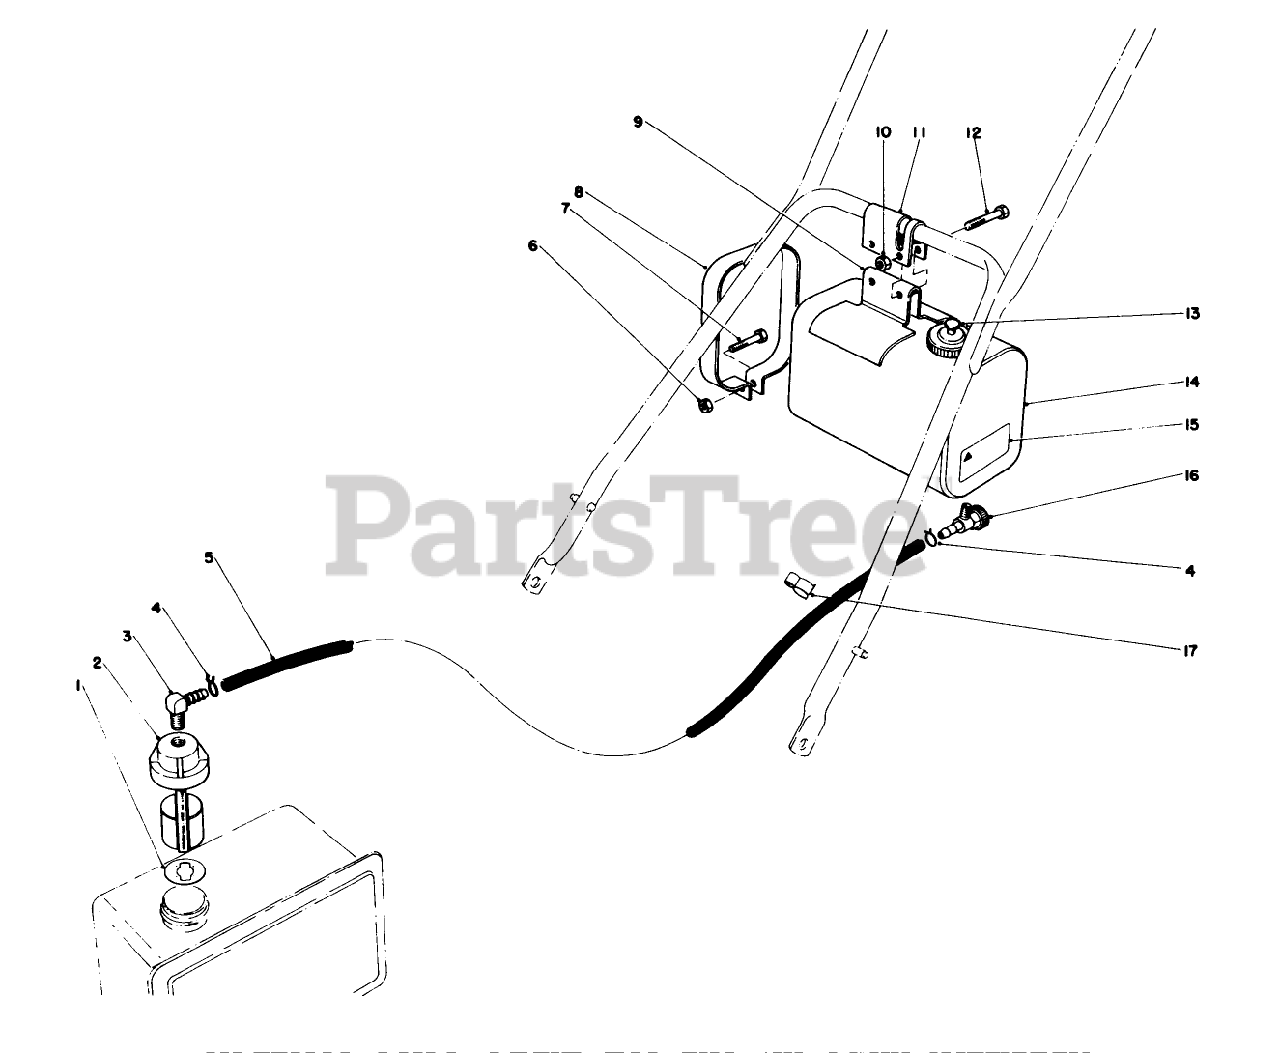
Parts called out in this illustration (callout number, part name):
2	FUEL CONT VALVE ASM
3	CONNECTOR-HOSE
7	SCREW-HH
12	SCREW-HH
